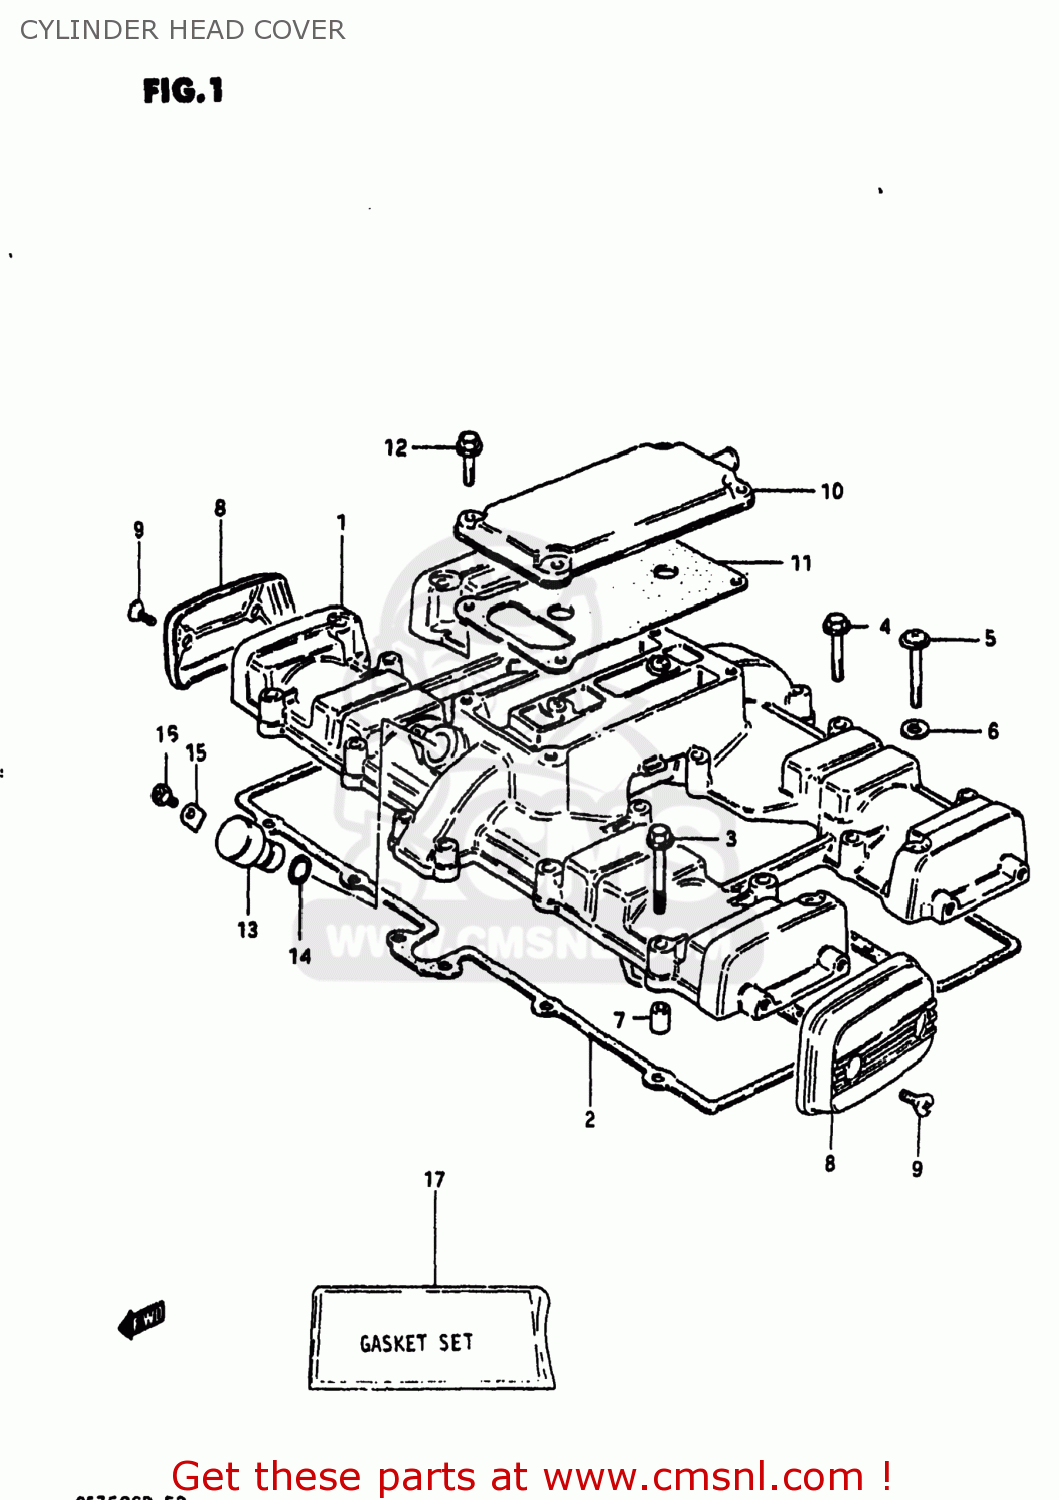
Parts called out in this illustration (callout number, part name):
1	COVER,CYLINDER HEAD
2	GASKET,CYLINDER HEAD COVER
3	BOLT (6X40)
4	BOLT
5	SCREW 6X40
6	WASHER
7	PIN(6.2X8X11)
8	CAP,CYLINDER HEAD COVER
9	SCREW(5X12)
10	COVER,BREATHER
11	GASKET (MCA)
12	BOLT
13	PLUG,TACH GEAR SLEEVE HOLE
14	SEAL,TACHOMETER DRIVEN
15	PLATE,TACH DRIVE GEAR SLEEVE
16	SCREW(5X12)
17	GASKET SET (MCA)
